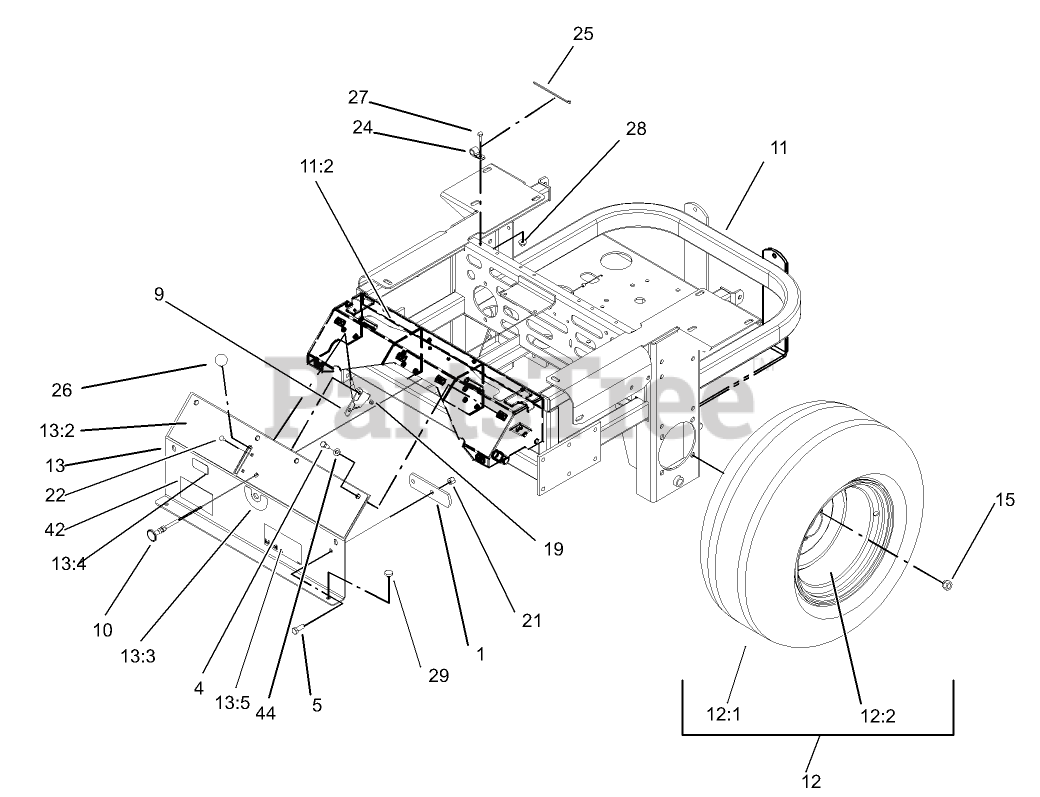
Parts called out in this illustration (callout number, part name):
1	STOP-BRAKE, PARK
4	SCREW-HH
5	SCREW-HH
9	THROTTLE CABLE ASM
10	CONTROL-CHOKE
11	Main Frame ASM
11:2	DECAL-CONSOLE, TOP
12	WHEEL AND TIRE ASM
12:2	WHEEL RIM
13	CONSOLE ASM
13:2	DECAL-PANEL, CONTROL
13:3	DECAL-VALVE, FUEL
13:4	DECAL-PROTECTION, EAR
13:5	DECAL-MOBIL 1
15	NUT-LUG
19	NUT-LOCK, NI
21	NUT-LOCK, NI
22	BOLT-CARR
24	CLIP-LOOM
25	TIE-PLASTIC
26	KNOB-BALL
27	SCREW-HH
28	NUT-HF
29	BUMPER
42	DECAL-TORO, Z255
44	WASHER-PLAIN
